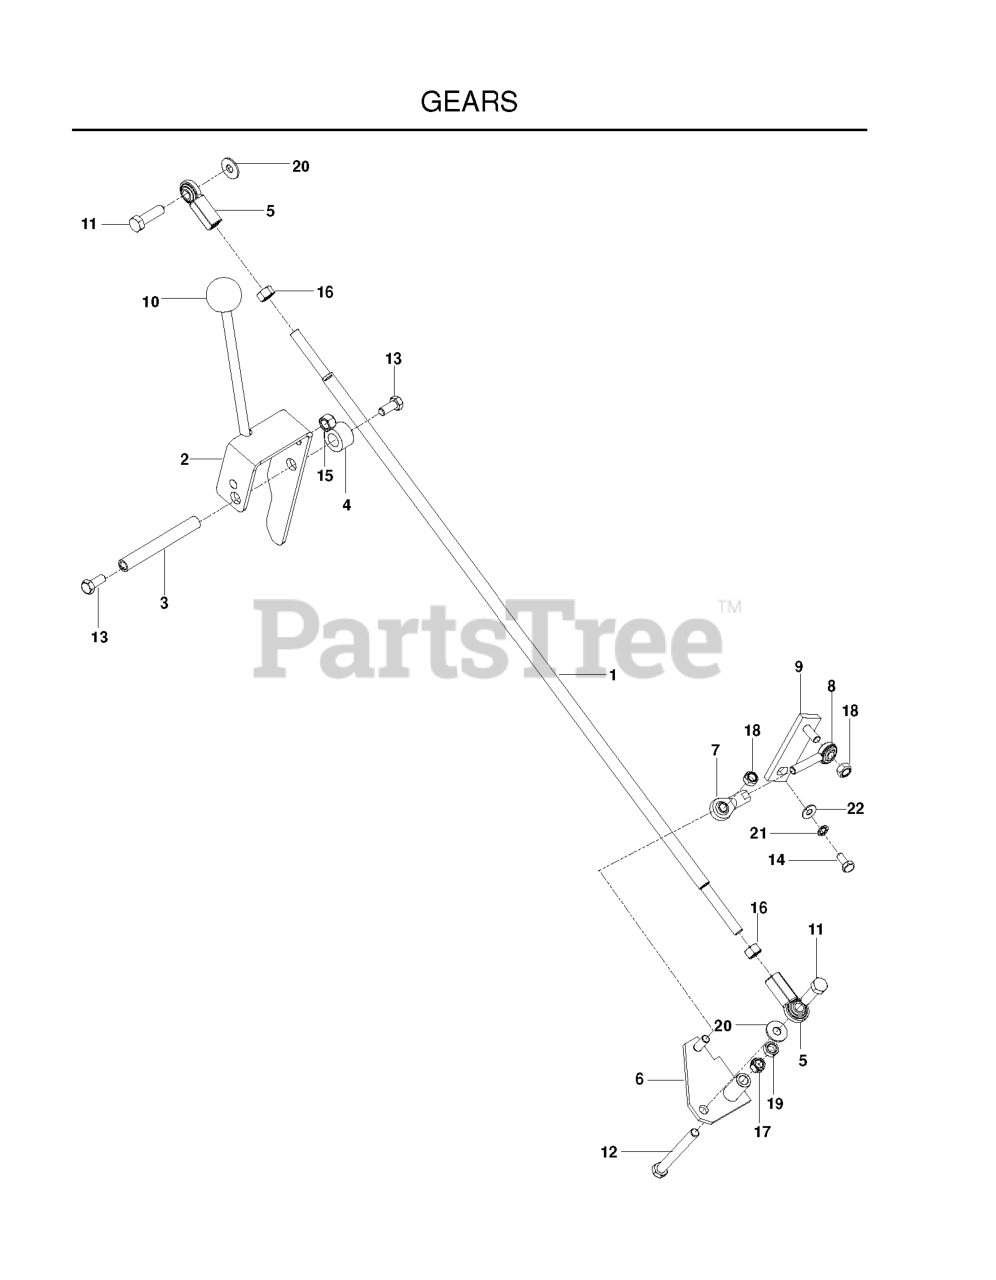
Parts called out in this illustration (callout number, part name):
1	SHIFT ROD, BLACK
2	SHIFT LEVER, ORANGE
3	SHAFT - SHIFT PIVOT
6	BELL CRANK SHIFT KIT
7	BALL JOINT, RIGHT HANDED
8	ROD END 5/16 MALE
9	KIT ARM TRANS SHIFT W/HDW
10	KNOB-SHIFT
11	HCS 3/8C X 1 1/4 GR5
12	HCS 3/8C X 3 1/2
13	HCS 5/16C X 3/4
14	HCS 1/4-28.X
15	NUT 3/8-16 NYLOC
17	NUT 3/8C CENTERBLOCK
18	NUT 5/16-24 TOP LK GRC ZD
19	NUT 3/8-16 HEX JAM
20	WASHER 5/16 FLAT
21	WASHER 1/4 INT TOOTH
22	WASHER 1/4 SAE
